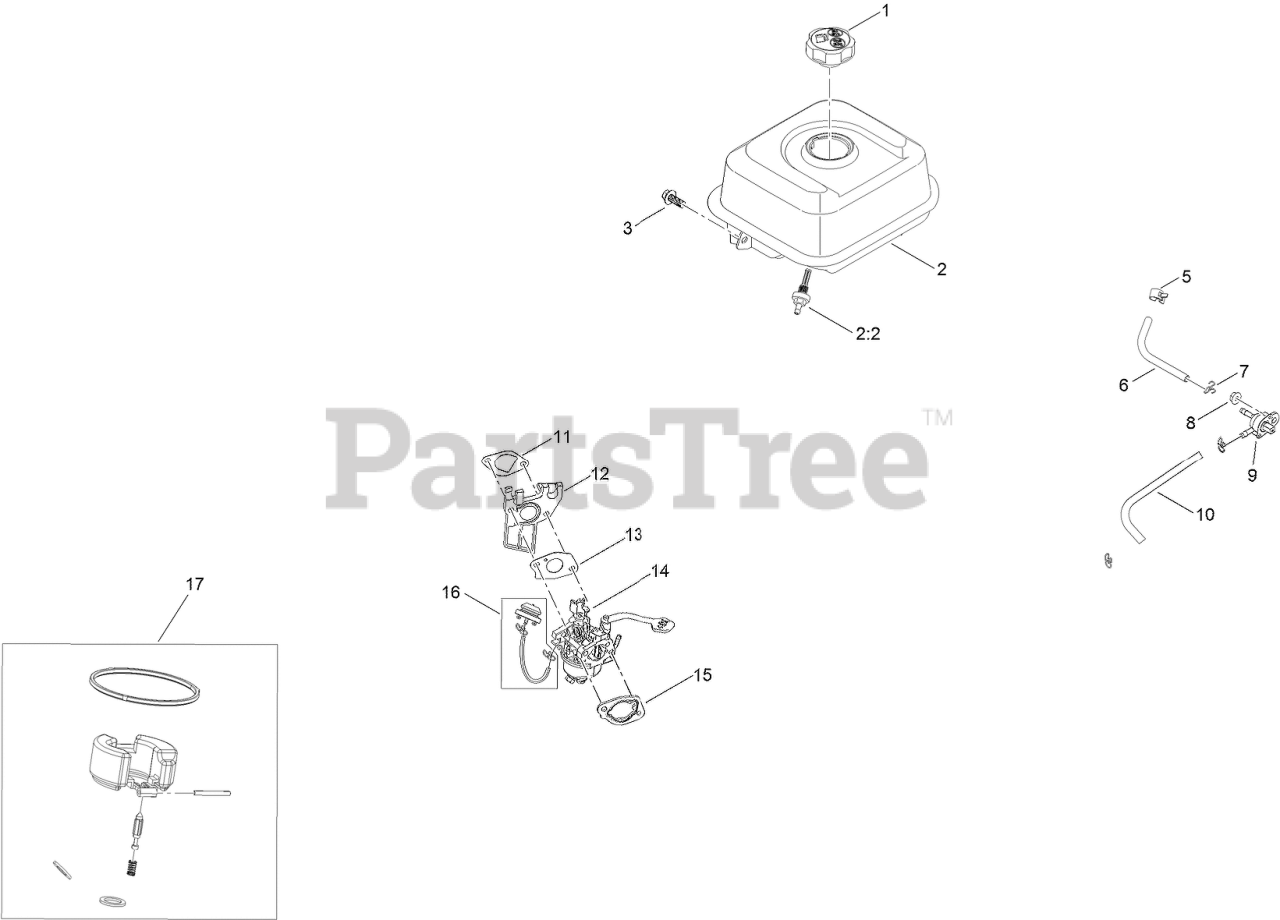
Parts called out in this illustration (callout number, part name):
1	CAP-FUEL (PHASE 3)
2	FUEL TANK AND FILTER ASM
2:2	FILTER-FUEL
3	SCREW-HHF
5	CLAMP-HOSE
6	HOSE-FUEL, FORMED
7	CLAMP-HOSE
8	NUT-FLANGE
9	VALVE-FUEL
10	HOSE-FUEL, FORMED
11	GASKET-CARBURETOR
12	INSULATOR-CARBURETOR
13	GASKET-CARBURETOR
14	CARBURETOR ASM
15	GASKET-CARBURETOR
16	PRIMER KIT
17	INTERNAL CARB SERVICE KIT
